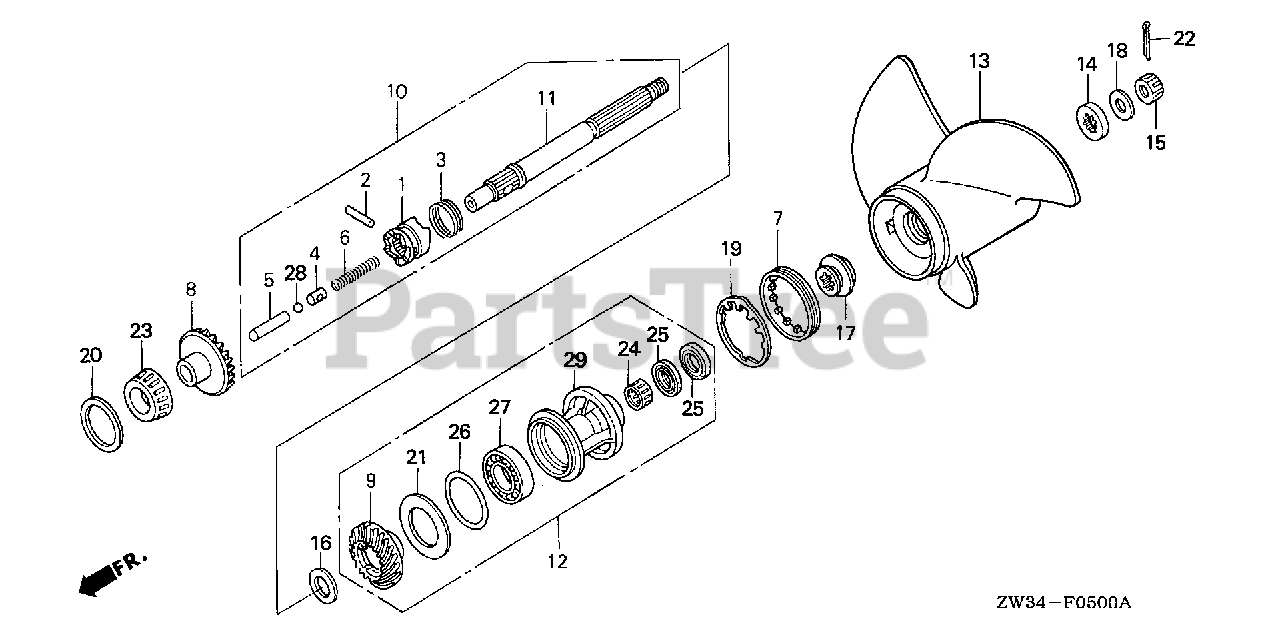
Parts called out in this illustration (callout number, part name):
1	SHIFTER, CLUTCH
2	PIN, SHIFTER (6.3X33)
3	RING, CROSS PIN
4	HOLDER, SHIFTER PIN
5	SLIDER, SHIFT
6	SPRING, SHIFT
7	NUT, GEAR CASE END
8	GEAR, FR. BEVEL
9	GEAR, RR. BEVEL
10	SHAFT ASSY., PROPELLER
11	SHAFT, PROPELLER
12	HOLDER ASSY., PROPELLER SHAFT
14	SPACER (10MM)
15	NUT, CASTLE (16MM)
16	WASHER (22MM)
17	WASHER, PROPELLER THRUST
18	WASHER (17MM)
19	WASHER, CLAW
20	SHIM, FR. BEVEL (51X57X0.10) (A)
20	SHIM, FR. BEVEL (51X57X0.15) (B)
20	SHIM, FR. BEVEL (51X57X0.30) (C)
20	SHIM, FR. BEVEL (51X57X0.50) (D)
21	WASHER, PLAIN (54MM)
22	PIN, COTTER (4.0)
23	BEARING (32X58X17)
24	BEARING, NEEDLE (22X28X20)
25	SEAL, WATER (22X35X7)
26	O-RING (66X5.7)
27	BEARING, RADIAL BALL (6007)
28	BALL, STEEL (#11) (11/32)
29	HOLDER, PROPELLER SHAFT
